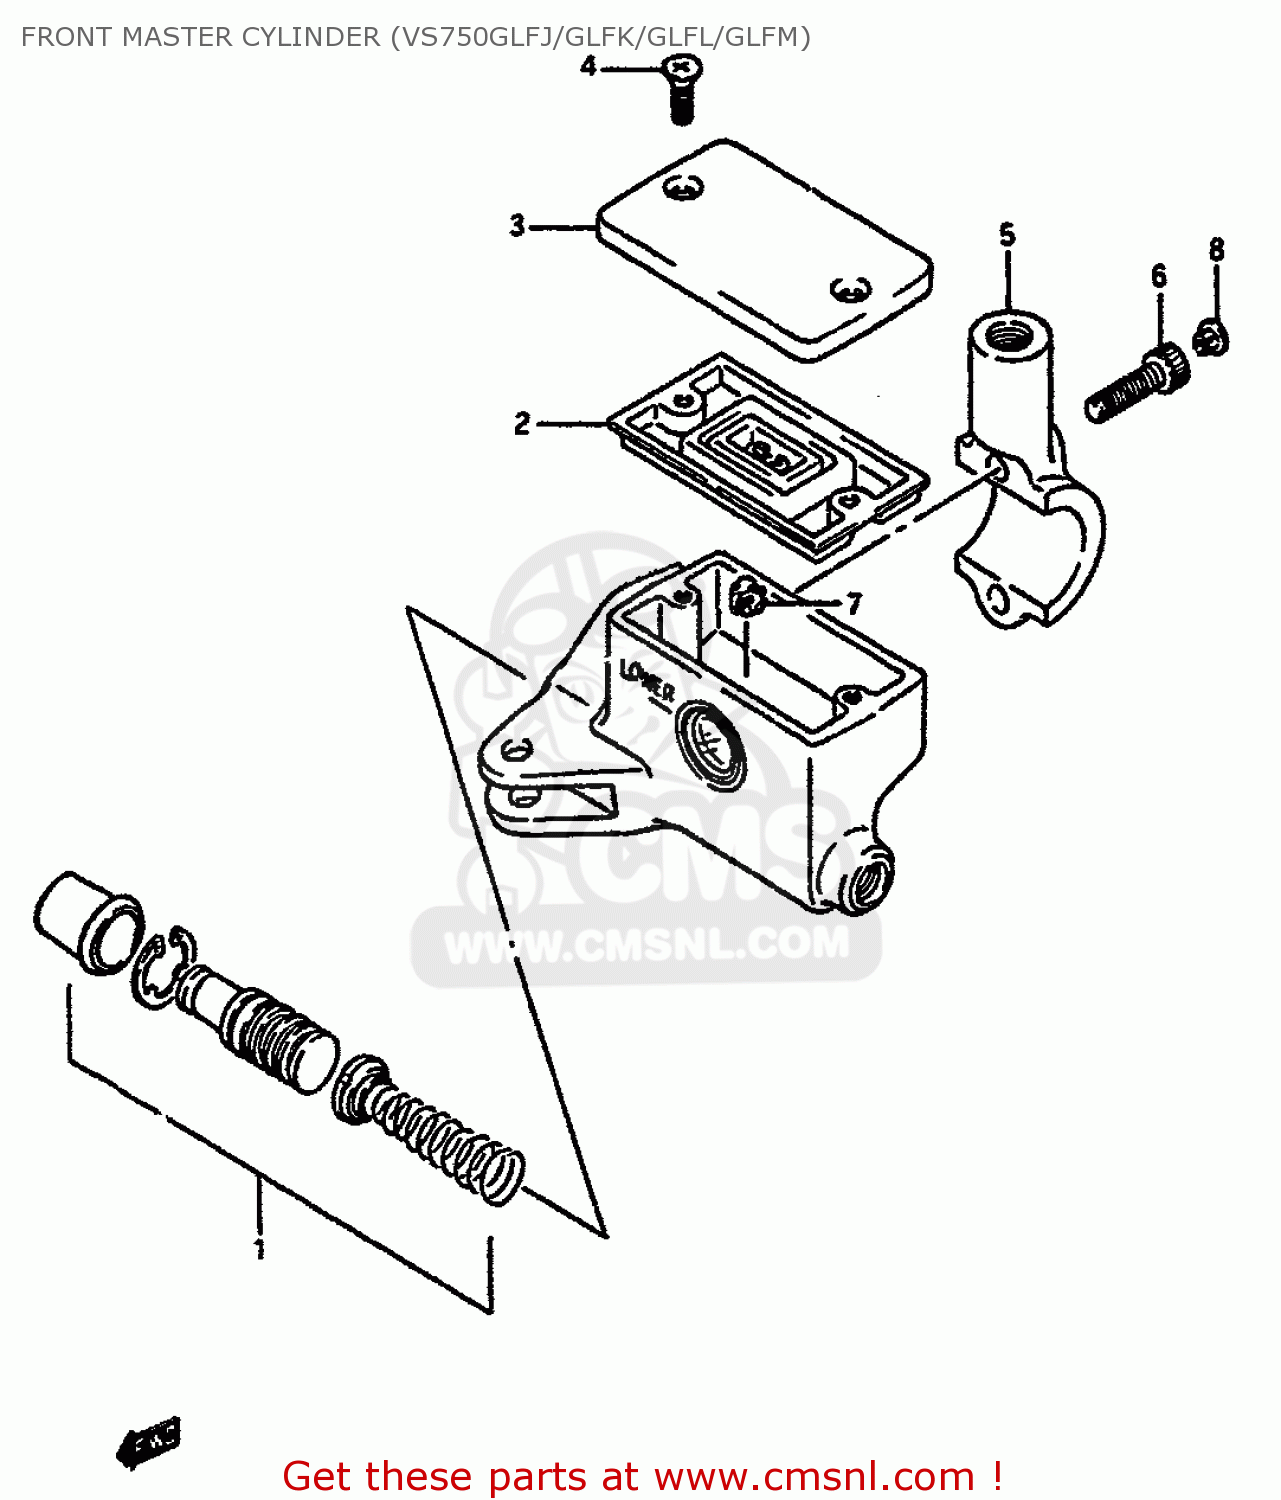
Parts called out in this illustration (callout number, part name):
1	CUP SET,MASTER CYLINDER
2	3-1
3	CAP
4	SCREW,RESERVOIR CAP
5	HOLDER
6	BOLT ,6X20
7	PROTECTOR
8	CAP(OD:10)
